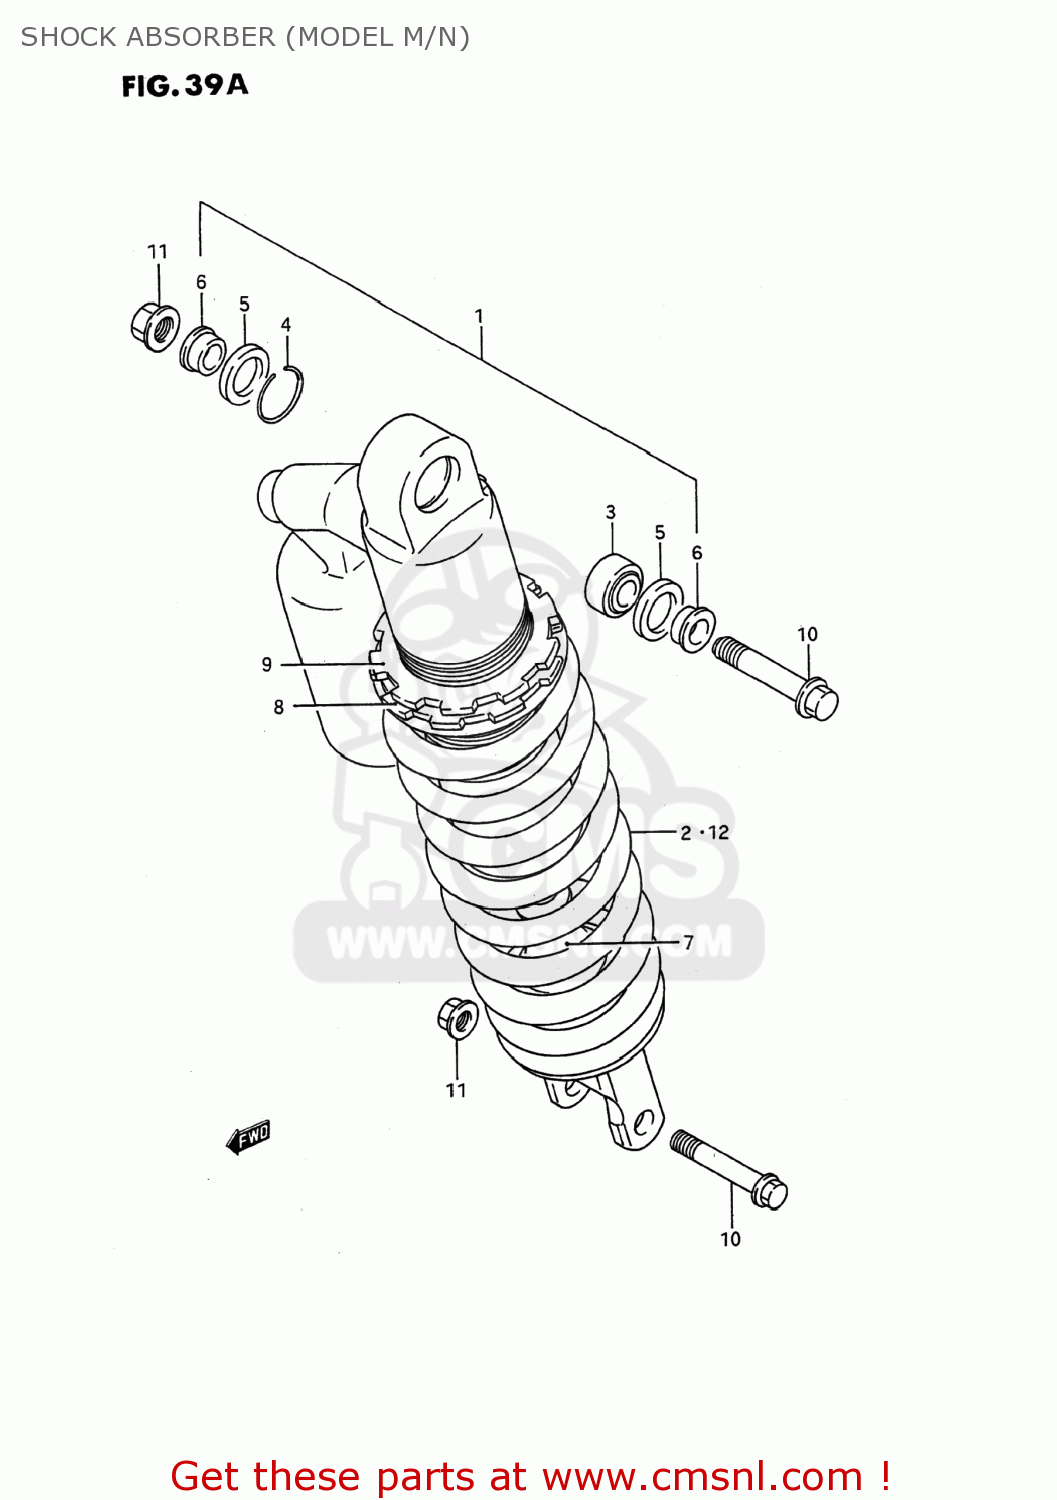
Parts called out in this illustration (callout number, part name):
1	ABSORBER ASSEMBLY,REAR SHOCK
2	SPRING
3	BEARING,RR CUSHION LEVER RR
4	RING,STOPPER
5	SEAL,DUST
6	COLLAR
7	ROD,PISTON
8	GUIDE,SPRING
9	NUT
10	BOLT,REAR SHOCK ABSORBER
11	NUT
12	SPRING,REAR (K=5.4)
